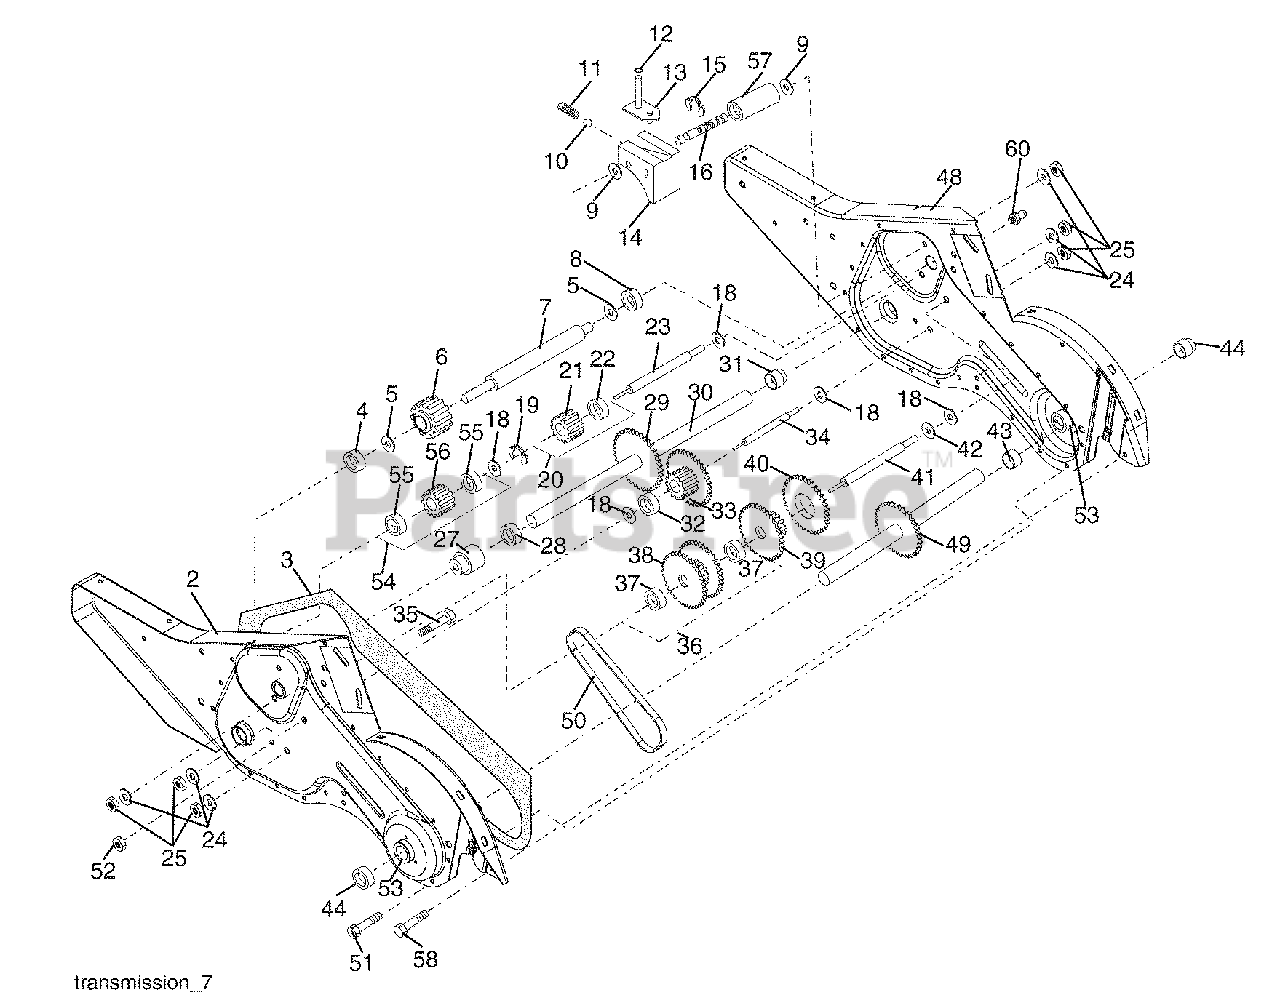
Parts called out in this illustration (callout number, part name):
1	Trans mis sion Assembly
2	Gearcase, L.H. w/Bearing
3	Gasket, Gearcase
4	Bearing, Needle
5	Washer, Thrust 5/8 x 1.10 x 1/32
6	Pinion, Input
7	Shaft, In put
8	Bearing, Needle
9	Washer, Seal
10	Ball, Steel
11	Spring, Shift, Fork
13	Arm, Shift
14	Fork, Shift
15	Ring, Klip
16	Shaft, Shift
19	Ring, Klip
20	Gear, As sem bly, Reverse Idler
21	Gear, Re verse Idler
22	Bearing, Needle
23	Shaft, Re verse Idler
24	Washer, Lock 7/16
25	Nut, Hex 7/16-20
27	Bearing, Shaft, Ground Drive L.H.
28	Spacer 0.765 x 1.125 x 1.23
29	Chain #35-50 Pitch
30	Ground Shaft Assembly
31	Bearing, Shaft, Ground Drive R.H.
32	Spacer 0.70 x 1.00 x 1.150
33	Sprocket and Gear Assembly
34	Shaft, Re duc tion (2nd)
35	Screw, Whiz, Lock 5/16-18 x 3-1/2
36	Sprocket Assembly w/Bearing
37	Bearing, Needle
38	Sprocket, Tine
39	Gear, Cluster, Red 1st & 2nd
40	Gear, Reverse
41	Shaft, Reduction (1st)
42	Washer, Thrust
43	Spacer 1.01 x 1.75 x 0.760
44	Seal Asm. OIl
48	Gearcase, R.H. w/Bearing
49	Shaft, Tine
50	Chain, Roller #50-50 Pitch
51	Screw 1/4-20 x 1/2
52	Nut, Hex 5/16-18
53	Bearing Kit, Tine Shaft
54	Gear, DRT Idler w/Bearing
55	Bearing, Needle
56	Gear, DRT Idler
57	Spacer, Split .52 x .64 x 1.04
58	Screw 1/4-20 x .875
60	Fitting Grease
